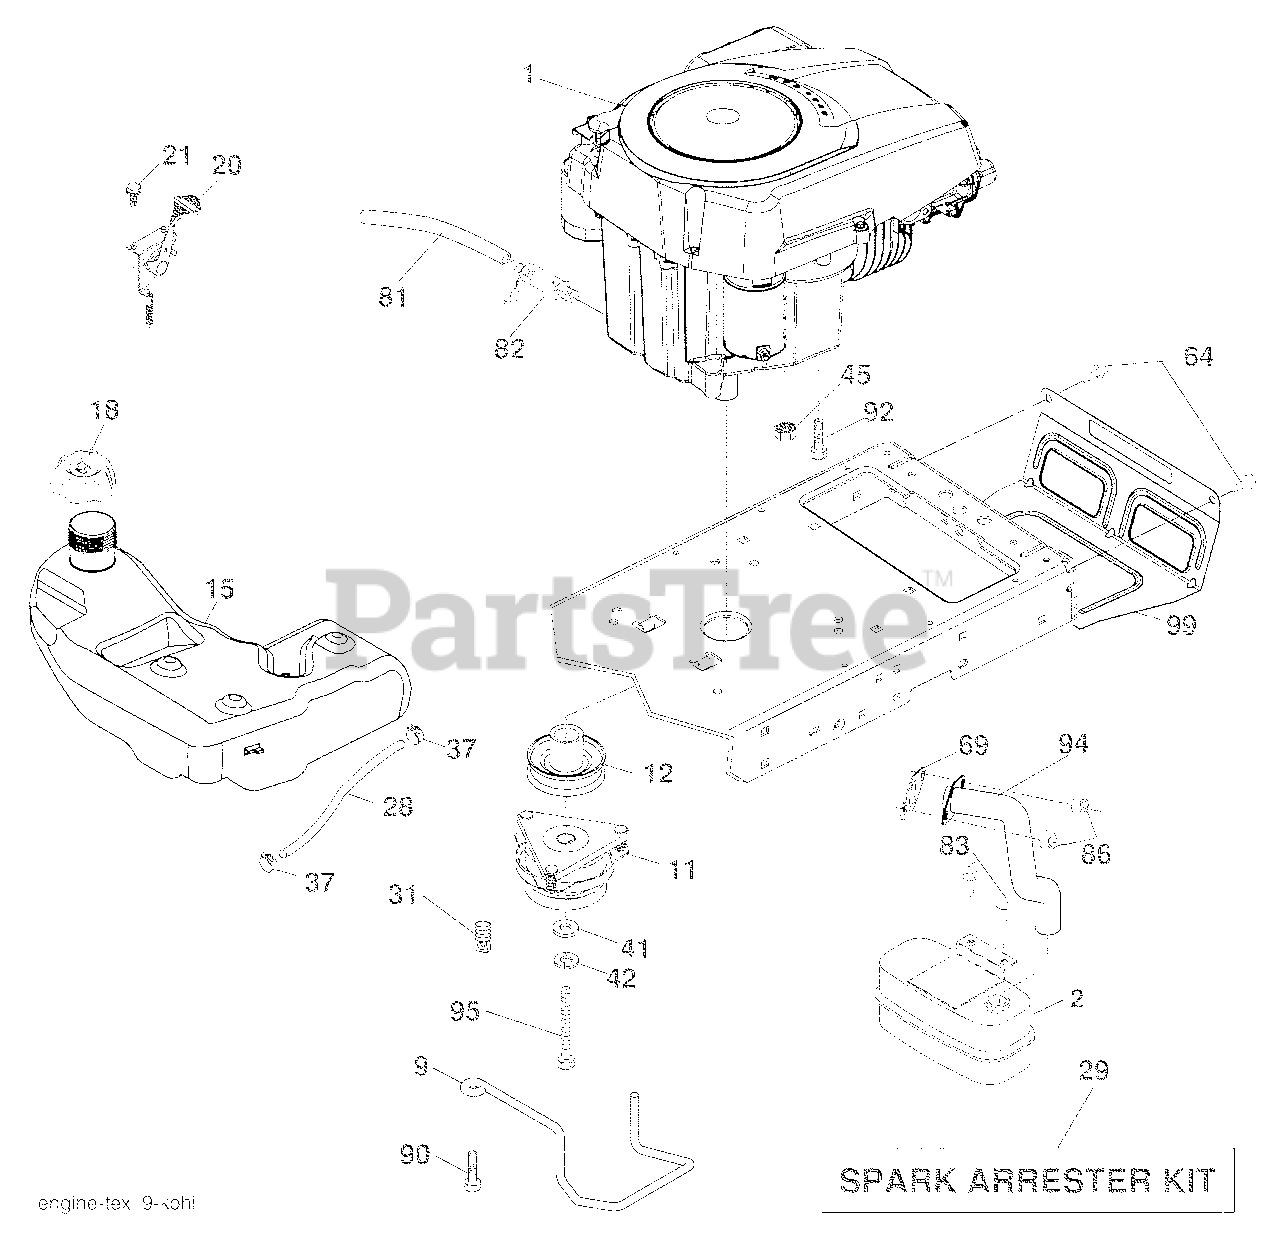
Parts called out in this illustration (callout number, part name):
9	Keeper Belt Engine
11	Clutch
12	Pulley Engine
15	Tank Fuel 4.0
18	Cap Asm
20	Control Throttle
21	Screw 1/4-20 x 1/2
28	Fuel Line
29	Spark Arrester Kit
31	Clip Push-In
37	Clamp Hose
41	Washer 1-1/2 OD x 15/32 ID x .250
42	Washer Lock 7/16
45	Nut Keps Hex 1/4-20 unc
64	Screw 3/8-16 x 3/4
81	Tube Drain Oil Easy
82	Plug Drain Oil
83	Bolt 5/16-18 x 3/4
86	Nut Hex Flange Toplock M8-1.25
90	Screw 3/8-16 x 1
92	Screw 3/8-16 x 1
94	Tube Exhaust
95	Bolt Hex 7/16-20 x 4 Gr. 5
99	Shield Browning
